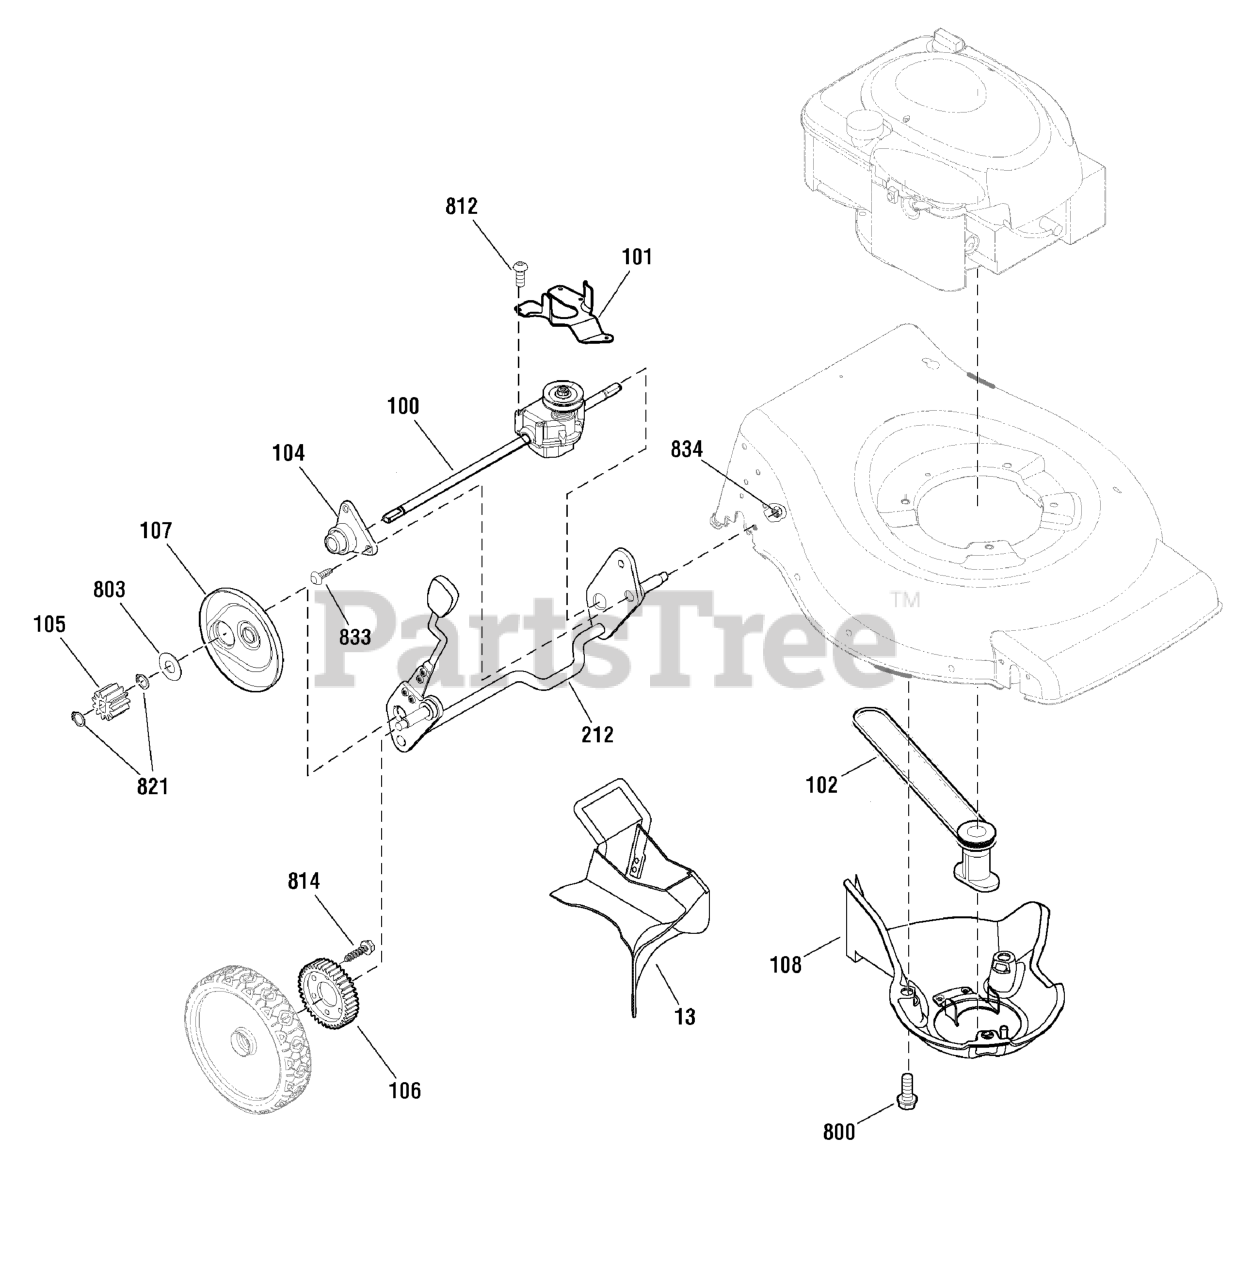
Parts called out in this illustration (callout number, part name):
13	MULCH PLUG
100	TRANSMISSION
101	BELT GUIDE, Transmission
104	SLEEVE ASSEMBLY, Rear Axle
105	GEAR, Pinion
106	GEAR, Drive
107	DUST COVER
108	BELT COVER ASSEMBLY
212	CROSSBAR ASSEMBLY, Rear
800	CAPSCREW, Hex Head, 3/8-16 x 1
803	WASHER, Thrust
812	SCREW, #10 x 1
814	SCREW, 1/4-15 x 3/4
821	RING, External Retaining
833	SCREW, Torx, 1/4-20 x 5/8
834	NUT, Flange Lock, 1/4-20
